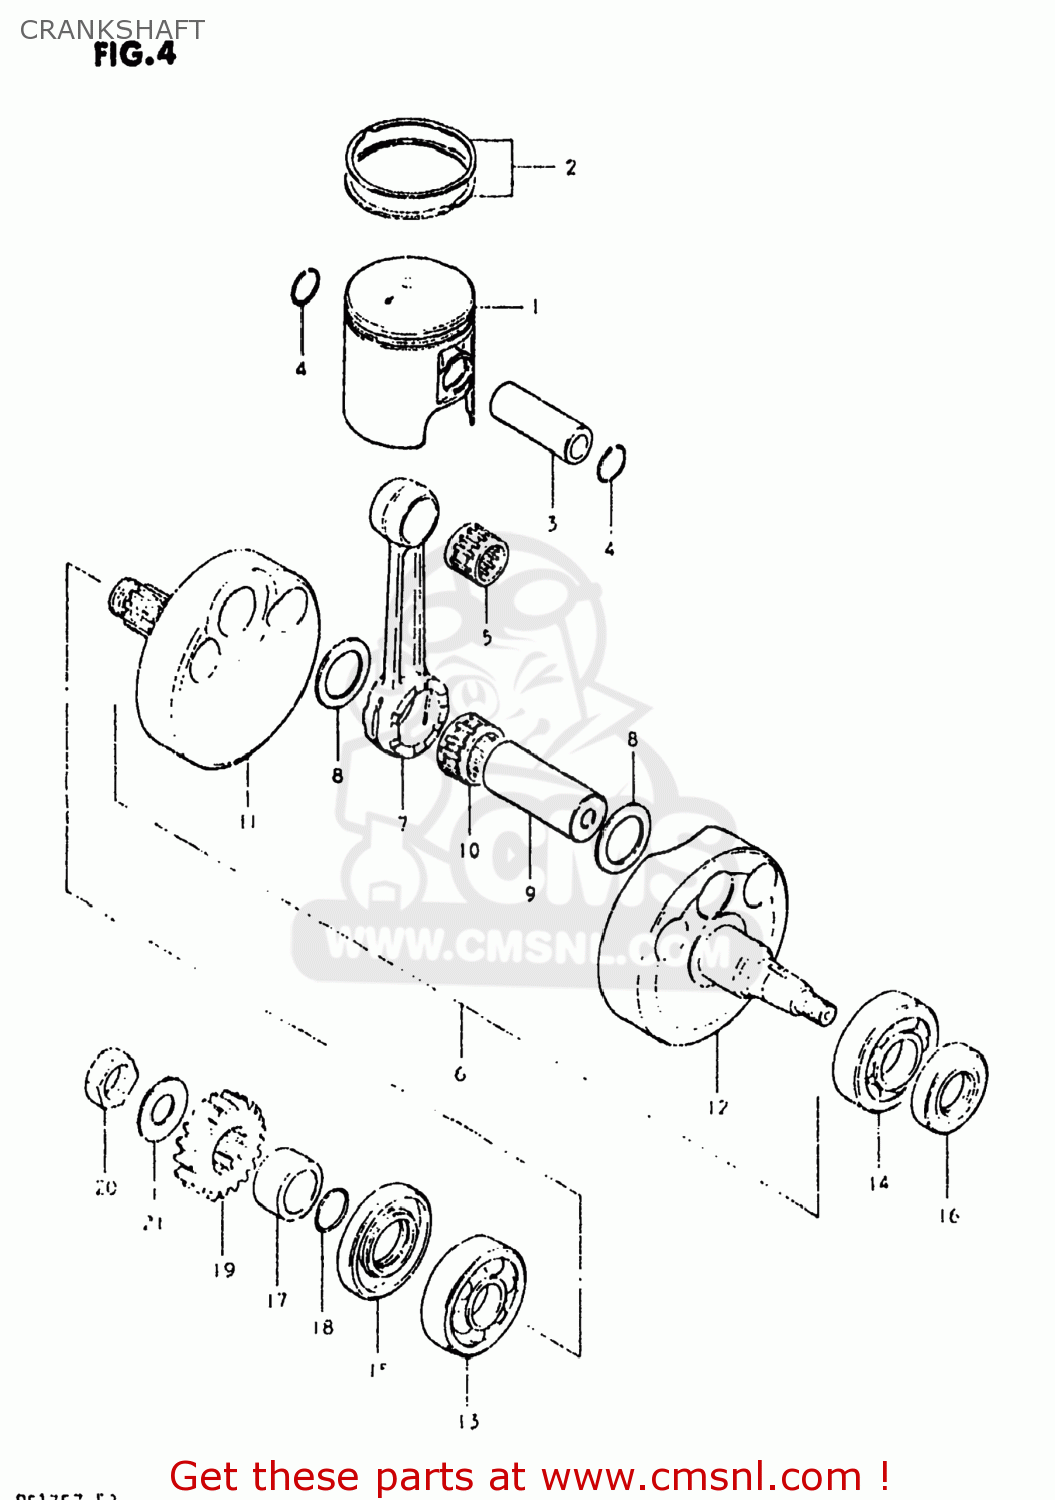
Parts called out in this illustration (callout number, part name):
1	PISTON
2	RING SET,PISTON
3	PIN,PISTON
4	RING,SNAP 16MM
5	BEARING
6	CRANKSHAFT ASSEMBLY
7	ROD,CONNECTING
8	WASHER(22X35X1)
9	PIN,CRANK
10	BEARING
11	CRANKSHAFT
12	CRANKSHAFT,LEFT
13	BEARING
14	BEARING
15	SEAL,OIL(29X47X8)
16	SEAL,OIL(25X44X7)
17	SPACER
18	O RING(D:2.4,ID:19.8)
19	GEAR,PRIMARY DRIVE
20	NUT
21	WASHER
